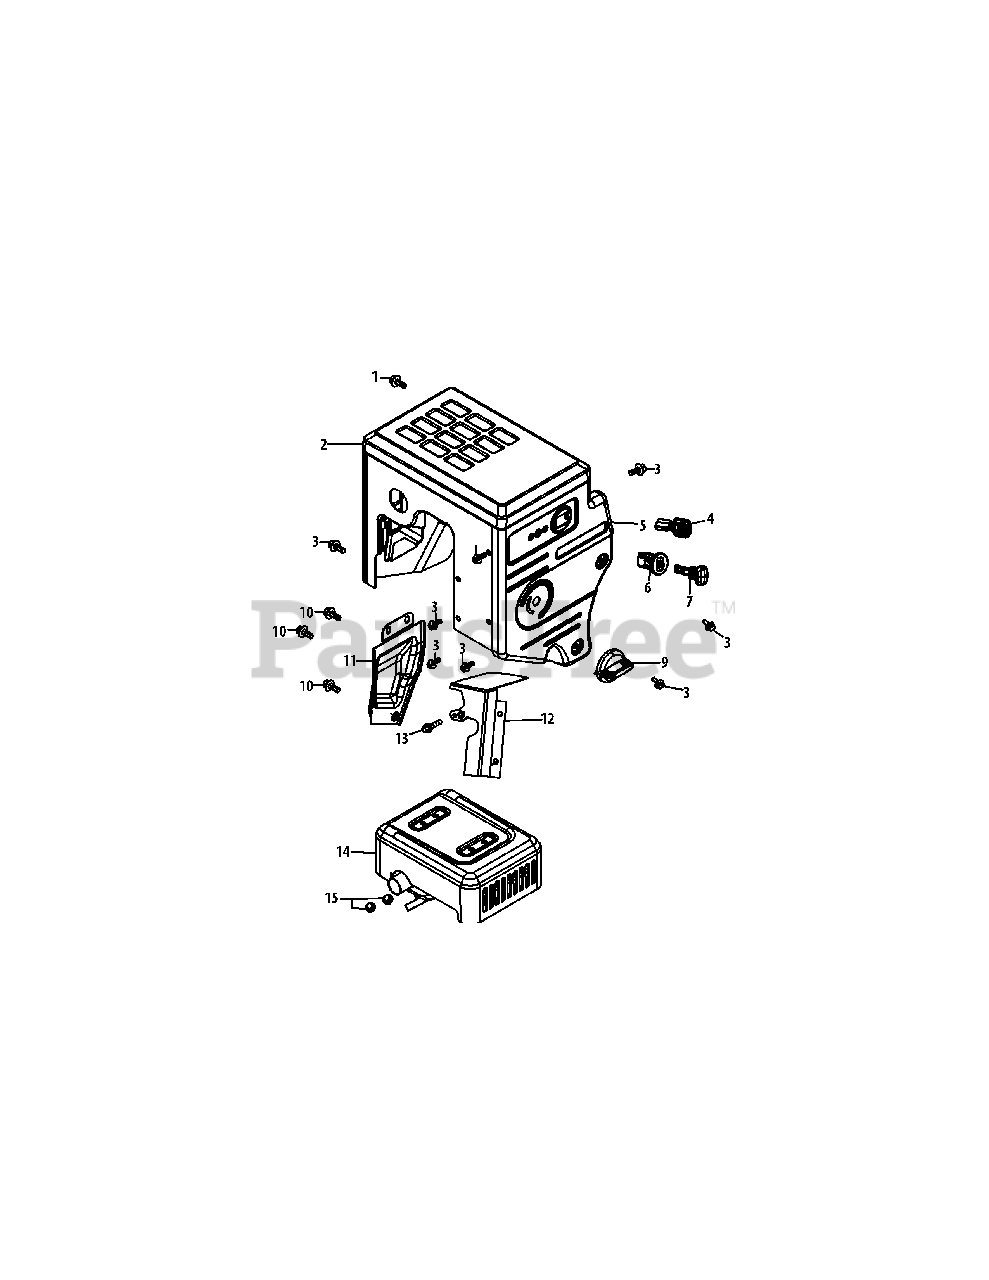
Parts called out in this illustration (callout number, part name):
1	Bolt M6×12
2	Muffler Shield
3	Bolt M6×12
4	Throttle Control Knob
5	Control Panel
6	Key Switch Base
7	Key
9	Choke Knob
10	Bolt M6×10
11	Exhaust Pipe Shield
12	Carb Isolator Bracket
13	Bolt M6×16
14	Muffler Assembly
